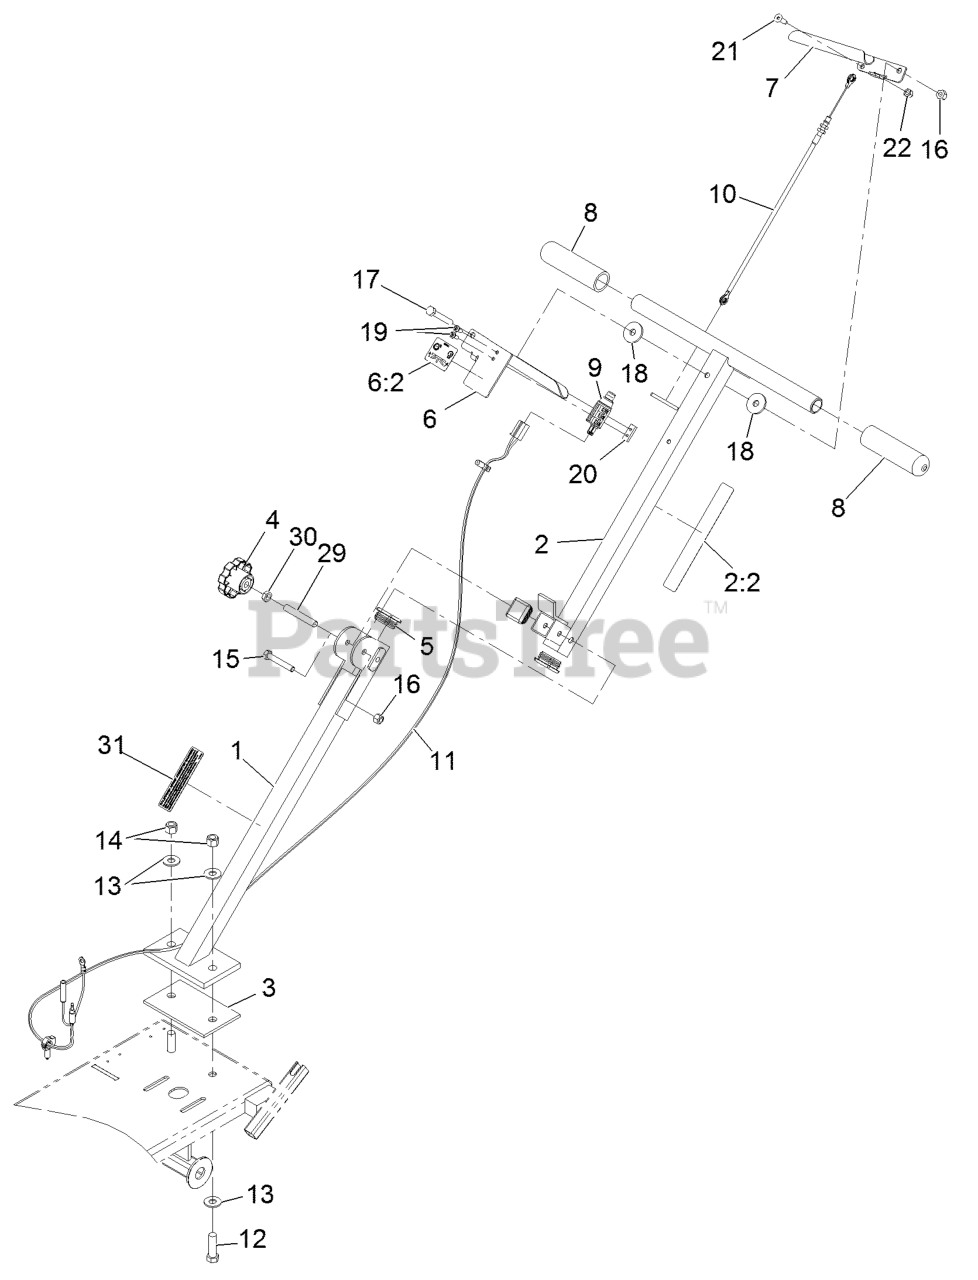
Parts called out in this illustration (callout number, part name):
1	HANDLE-LOWER
2	HANDLE ASM
2:2	DECAL-CAUTION
3	GASKET-HANDLE
4	KNOB
5	PLUG-TUBE
6	Plunger Handle Asm,
6:2	DECAL-ENGAGE
7	HANDLE-THROTTLE
8	GRIP-HANDLE
9	SWITCH-PLUNGER, NC (W/COV
10	CABLE-THROTTLE
11	HARNESS-WIRE
13	WASHER-FLAT
14	NUT-LOCK, NI
15	SCREW-HH
16	NUT-LOCK, NI
17	SCREW-HH
18	WASHER
20	PLATE-TAPPED
21	SCREW-TORX
22	NUT-LOCK, NI
29	SCREW-HSH
30	NUT-JAM
31	DECAL-ARRESTER, SPARK
